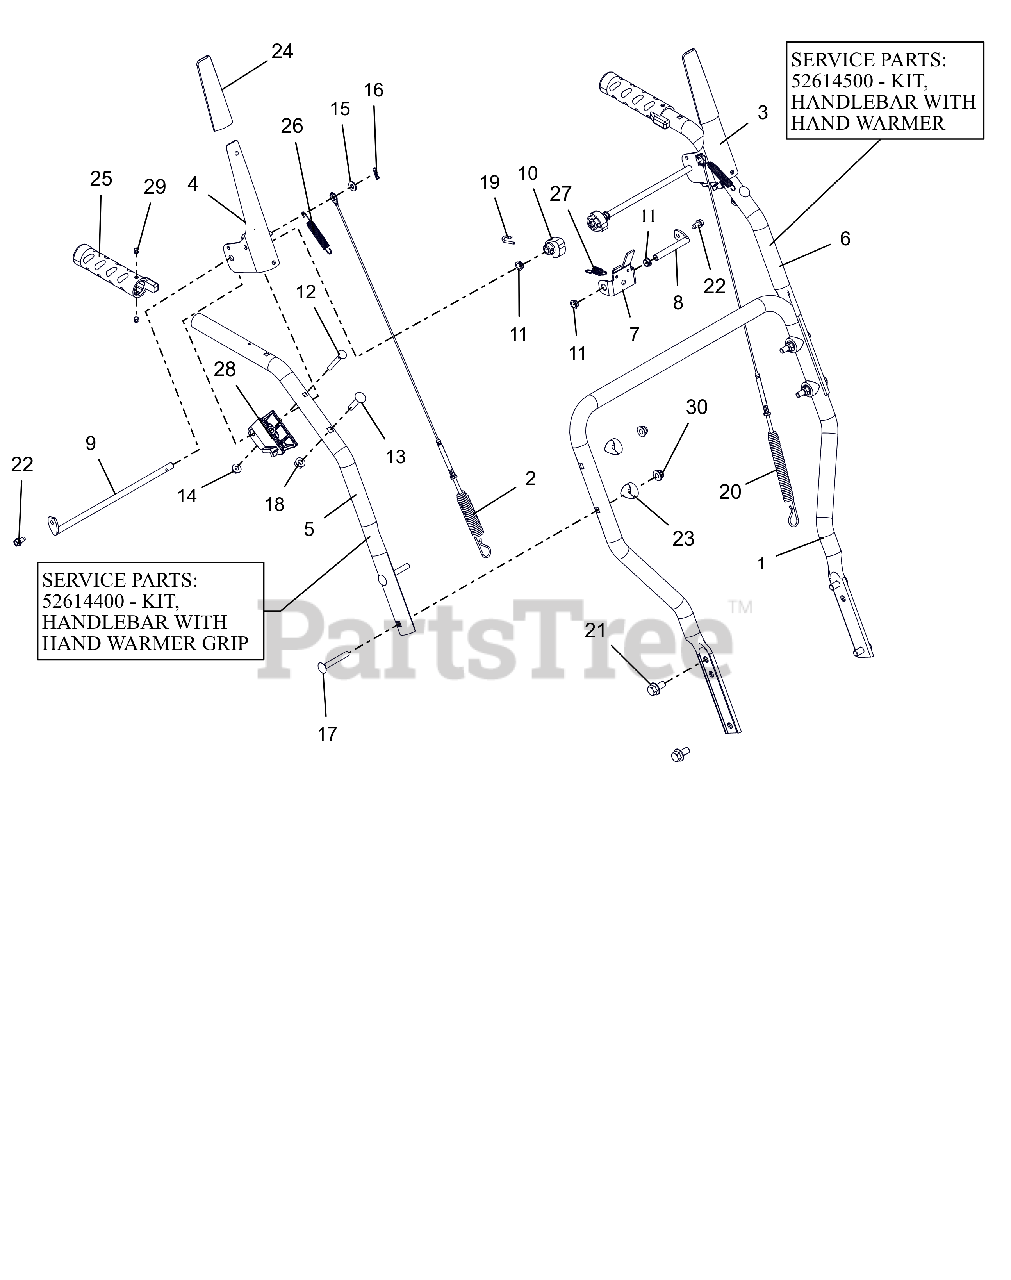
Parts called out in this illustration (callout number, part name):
1	HANDLEBAR, LOWER
2	CABLE, AUGER (DELUXE & PRO)
3	LEVER, CLUTCH-LH
4	LEVER, CLUTCH-RH
5	HANDLEBAR, UPPER - RH
5	KIT, HANDLEBAR HW RH
6	HANDLEBAR, UPPER - LH
6	KIT, HANDLEBAR HW LH
7	BRACKET, INTERLOCK ARM
8	ROD, PIVOT - INTERLOCK
9	ROD, PADDLE MOUNT - PRO
10	CAM, INTERLOCK
11	BUSHING, POLYLINER-.38 SNAPIN
12	BLT-RDHDXLSQNK .25-20X2.0 G5YZ
13	BLT,RHSN .31-18X1.50 G5 ZCC
14	NUT-LK-CTR-FLG .25-20 ZC120
15	WSHR,FLT .281X.625X.065 ZCC
16	PIN, HAIR #178 .06X.77 ZCC
17	BLT, RHSN .31-18X2.25 G5 ZCC
18	NUT-LK-TOP-FLG .312-18 GF ZCC
19	PIN, SPRING CLIP
20	CABLE, UPPER TRACTION
22	SCR-TAP .25-20X.50 HWH ZCC
23	SPACER, HANDLEBAR
24	SLEEVE, CLUTCH PADDLE-GRAY
25	GRIP,HEATED HANDLE-GRAY
26	SPRING, EXTENSION
27	SPRING-EXT .047X.438X1.45
28	BLOCK, CLUTCH PADDLE
29	RVT-POP #43 .125X.313 STL ZINC
30	NUT,LK-NYL-FLG .31-18 G5ZC120
